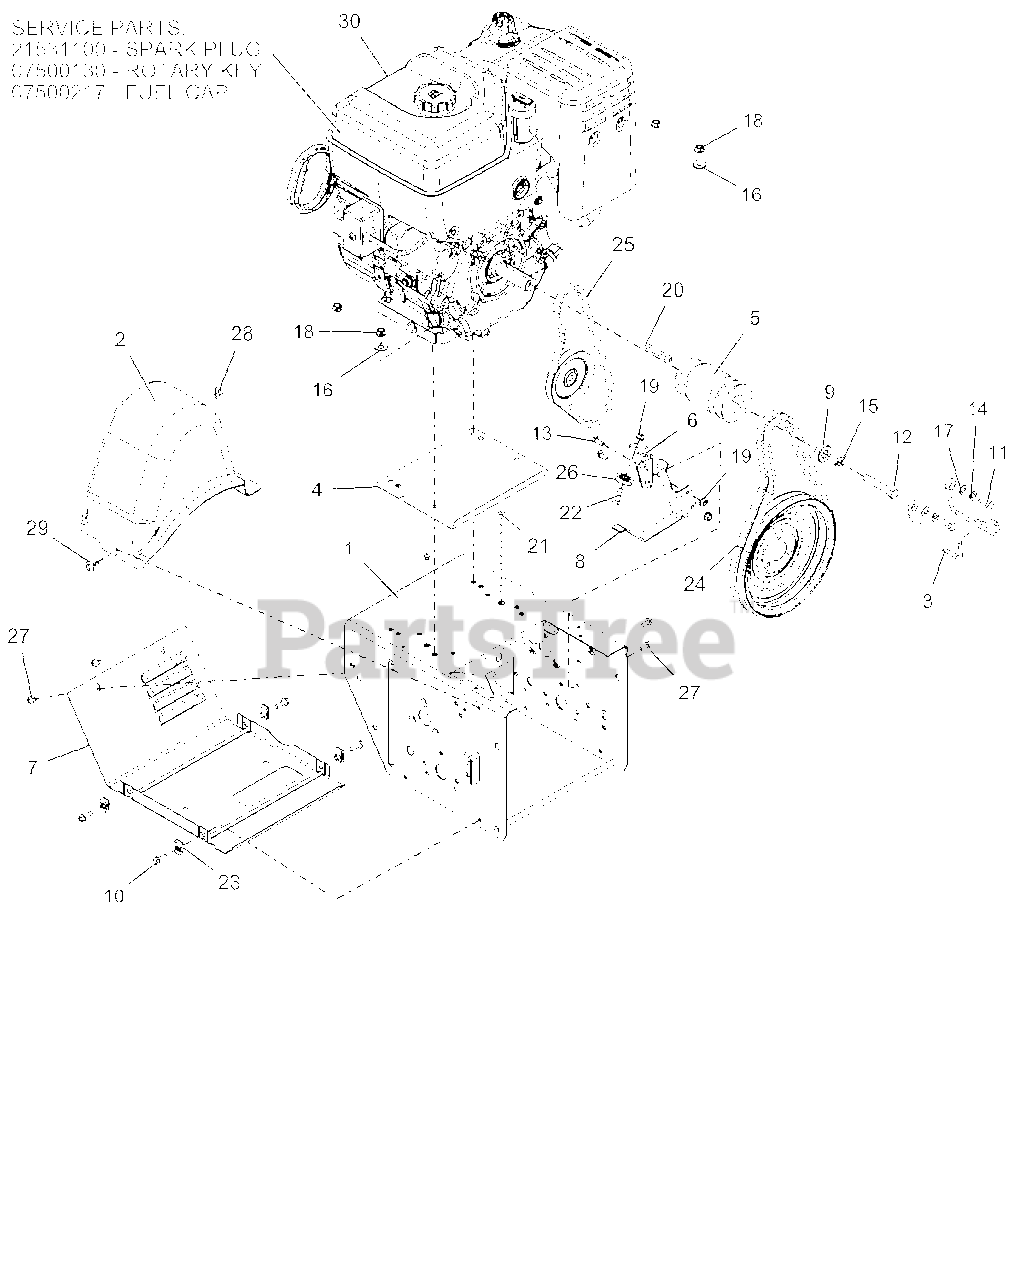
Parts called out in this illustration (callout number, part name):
1	PRO HYDRO FRAME, MAIN
2	COVER, BELT-LARGE PRO
3	FINGER, BELT
4	BAFFLE,ENGINE-PRO SERIES
5	SHEAVE, COMBO HYDRO WHEEL 4L
6	BRACKET, CLUTCH CABLE
7	COVER, BOTTOM - VENTILATED
8	FINGER, BELT - FLAT
9	BSHG-SPACER .47X1.25X.50
10	BLT-HEX .25-20X.75 HWH YZ GR5
11	BLT-HEX .31-24X.75 YWZC GR5
12	BLT-HEX .44-20X2.50 GR5 YWZC
13	@BLT-RDHDSQNK .25-20X.75 G5YZ
14	WSHR-LK .312X.097 HVY YWZC
15	@WSHR-LK .44X.109 REG YWZC
16	@WSHR-FL-STL.38X.875X.083 YWZC
17	@WSHR-FL-STL.344X.688X.065YWZC
18	@NUT-LK-CTR-FLG .31-18 YZ GR F
19	@NUT-LK-TOP-FLG .25-20 YWZC
20	KEY .25X.25X2.25
21	RVT-POP .187 YZ
22	BOLT, SHLDR-.375X.375X.25-20
23	NUT-RTNR .25-20X.56
24	V-BELT, HA-RAW EDGE (SET)
25	V-BELT, 4L-WRAPPED
26	PULLEY, CABLE
27	SCR-TAP .25-20X.50 HWH TR YWZ
28	SCR-TAP .25-20X.50 LGHWH TR YZ
29	SCR-TAP .25-20X.5 CAPTIVE
30	PLUG, SPARK 20HP B&S VANGUARD
30	KEY, IGNITION ROTARY B&S
30	ENGINE, BRIGGS PF 2100, 120V
30	CAP, FUEL - BRIGGS & STRATTON
